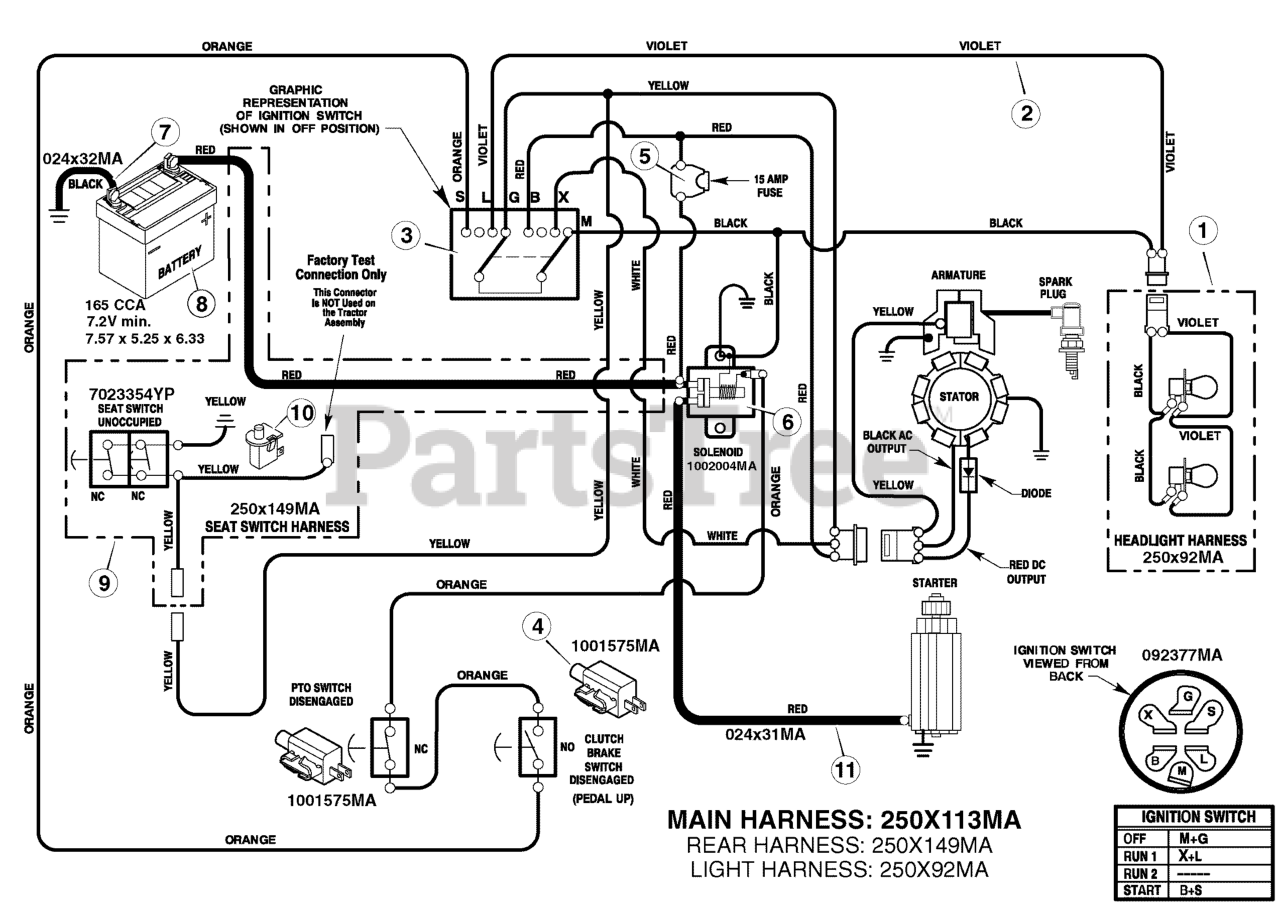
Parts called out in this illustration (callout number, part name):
1	HARNESS, Headlight
2	HARNESS, Chassis Wire
3	SWITCH, Ignition, Indak
4	SWITCH, No Limit, Snap-In
6	SOLENOID, 3 Pole
7	CABLE, Battery Ground
8	BATTERY, 12 Volt, 230 CCA
9	WIRING HARNESS, Seat Switch
11	CABLE, Battery
